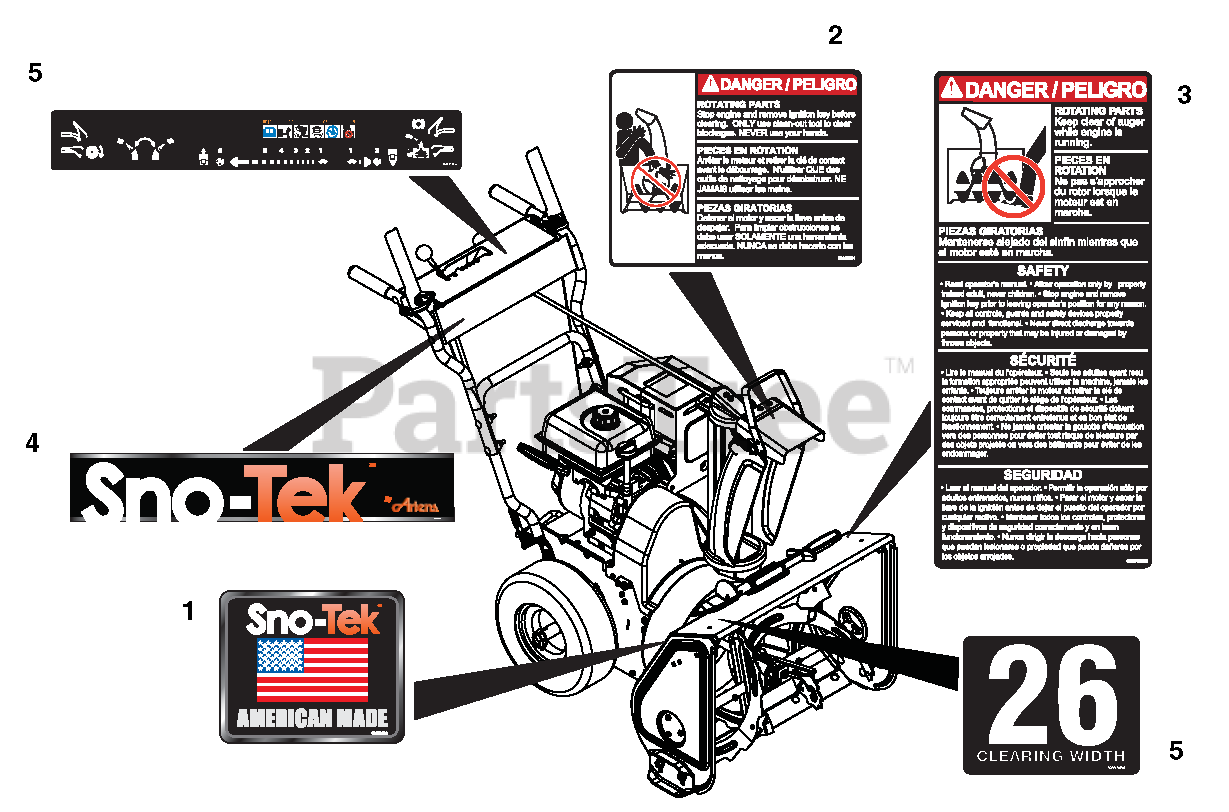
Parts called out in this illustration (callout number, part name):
1	DECAL, SNO-TEK - AMERICAN MADE
2	DECAL, DANGER - ROT. PARTS
3	DECAL, DANGER
4	DECAL, DASH - SNO-TEK
5	DECAL, CONTROL, COMPACT/DELUXE
6	DECAL, HOUSING SNO-TEK 24
